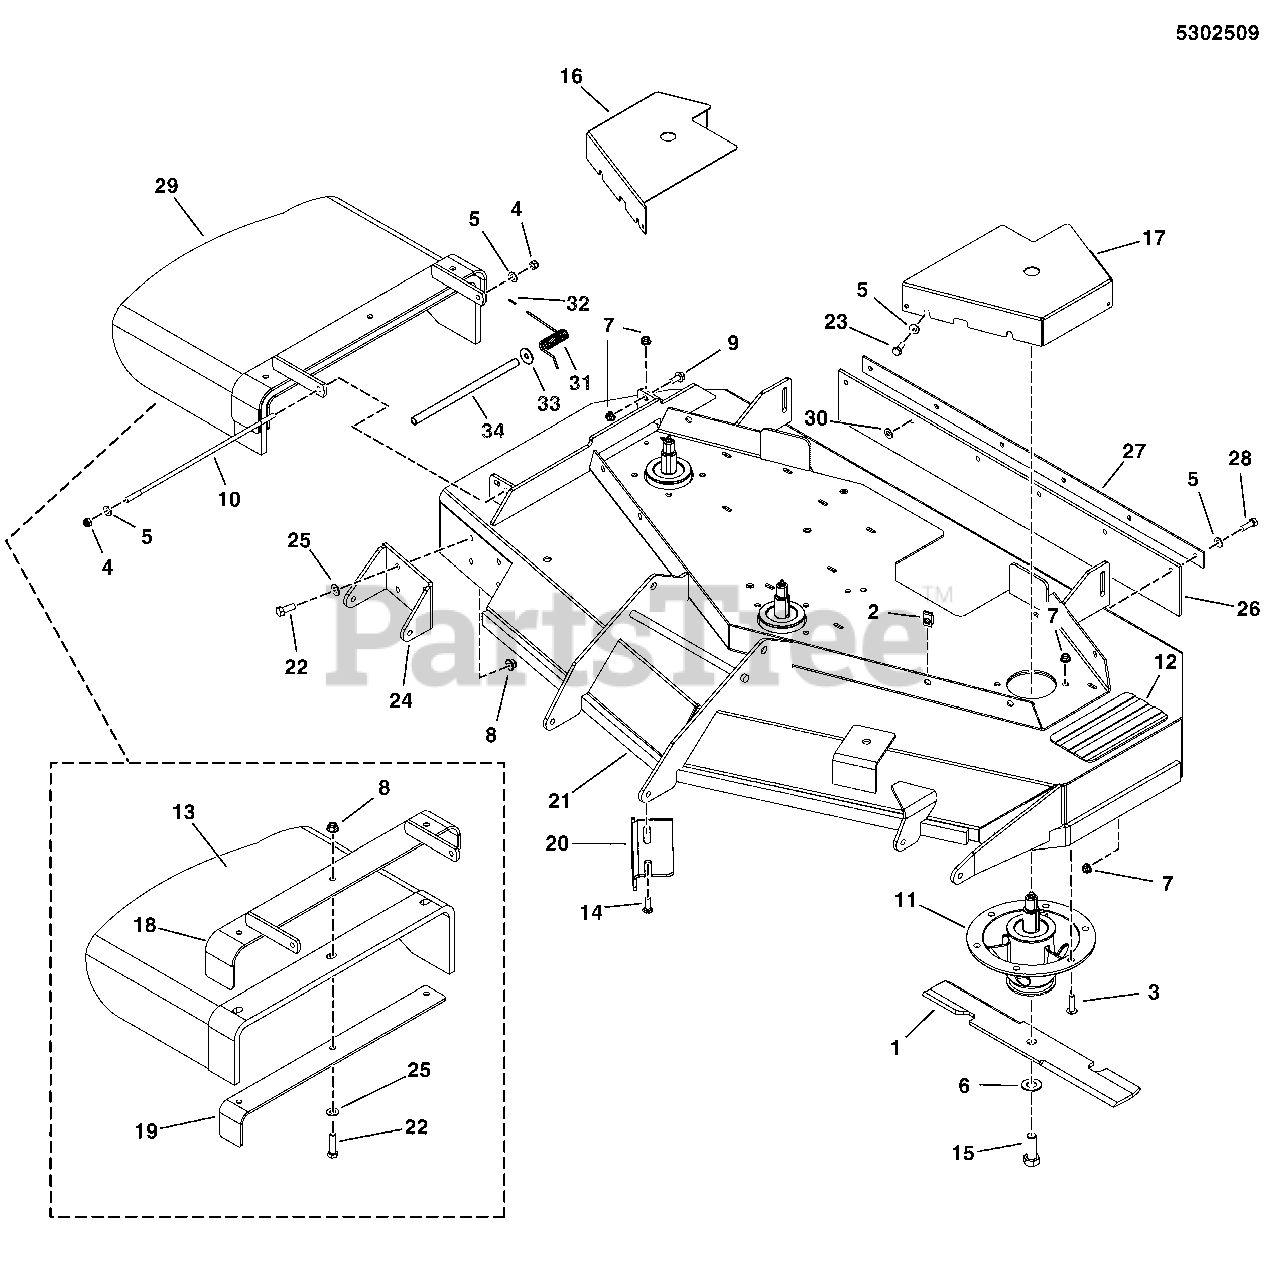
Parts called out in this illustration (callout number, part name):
1	BLADE, 18 X .25 X 2.5, 1 X 3.5 (SET OF THREE)
1	BLADE, 18 X .25 X 2.5, 1 X 3.5
2	BODY CLIP, 5/16-18-7GA MATERIAL
3	BOLT, 3/8-16 X 1, FLANGE, GD 5, CZ
4	NUT, 5/16-24 HEX NYLON LOCK
5	WASHER, 5/16" SAE
6	WASHER, 5/8 GRADE 8, YZ
7	NUT, 5/16-18 HEX NYLOCK FLANGE
8	NUT, 3/8-16 HEX NYLOCK FLANGE
9	SCREW-HEX WZ LOCK FLNG 5/16-18X0.750BLK
10	ROD MOUNT, CHUTE 61"
11	SPINDLE ASSM, CAST IRON 8.0-6 BOLT
12	SAFETY WALK, 4.00 X 7.50
13	CHUTE, DISCHARGE, RUBBER, 61/72
14	BOLT, 5/16-18 X 3/4, CARRIAGE
15	BOLT, 5/8-11 X 1-3/4 GD8
16	GUARD, 52" DECK - RH - RED
17	GUARD, 52" DECK - LH - RED
18	WELD, FRAME, CHUTE, 61 - SNP RED
19	SUPPORT, DISCHARGE CHUTE - BLK
20	PLATE, DEFLECTOR - RED
21	DECK SHELL W/DECALS, 52, S150XT
22	BOLT, 3/8-16 X 1-1/4 GD5
23	BOLT, 5/16-18 X 3/4 GD5
24	PLATE, BRACKET, ANTI SCALP - RED
25	WASHER, 3/8 SAE
26	FLAP, STRIPER, 52 DECK
27	PLATE, SUPPORT - BLK
28	BOLT, 5/16-18 X 1 GD5 YZ
29	KIT, DISCHARGE CHUTE
30	5/16 PUSH-ON NUT RETAINER, STL, CZ
31	SPRING, TORSION
32	CAP, PROTECTOR, .120 ID
33	WASHER, 5/16 FENDER
34	TUBE, 1/2 X 3/8 X 10.75 BLACK POLY
